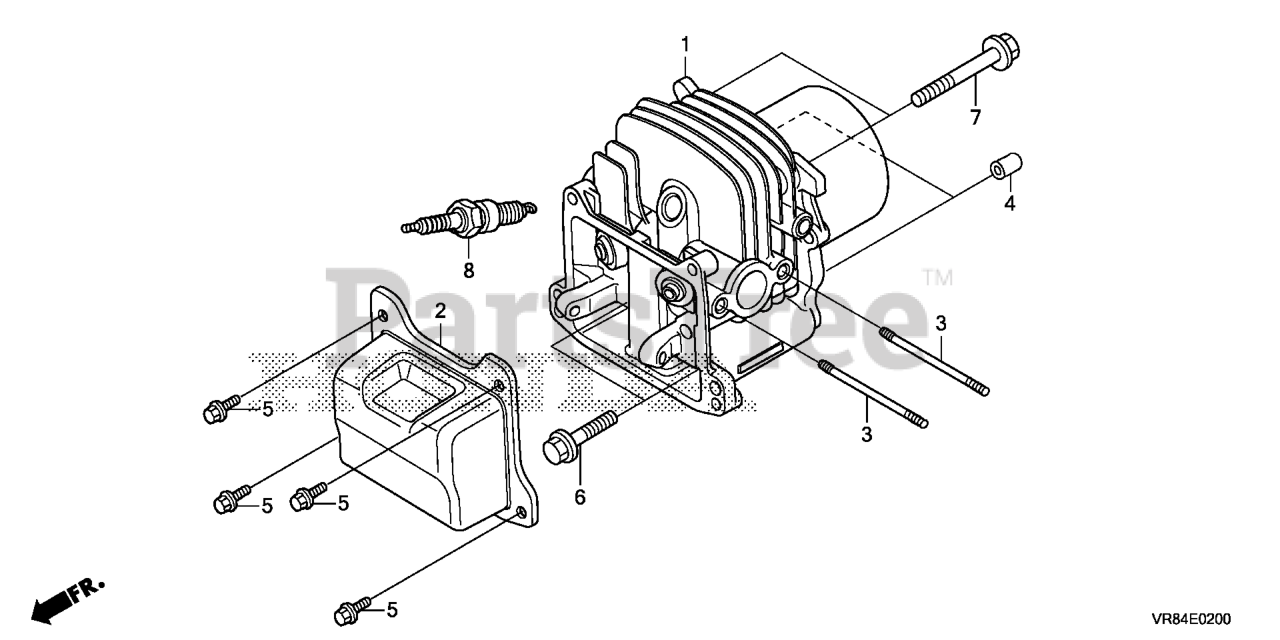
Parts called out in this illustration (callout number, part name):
1	CYLINDER
2	COVER, HEAD
3	BOLT, STUD (6X82) (CT200)
4	PIN A, DOWEL (8X14)
5	BOLT, FLANGE (6X14)
6	BOLT, FLANGE (8X25)
7	BOLT, FLANGE (8X40)
8	SPARK PLUG (BPR5ES) (NGK)
